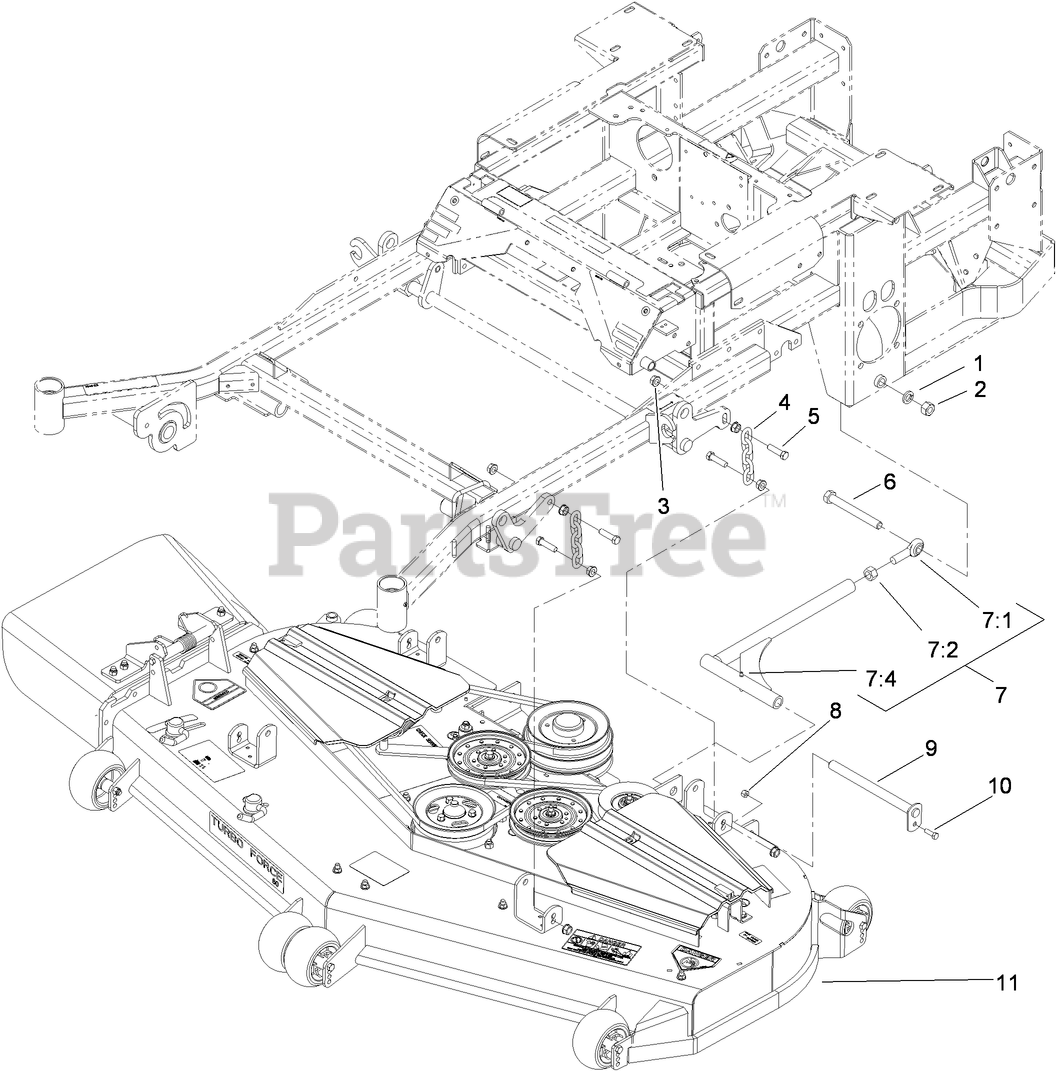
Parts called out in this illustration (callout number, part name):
1	WASHER-LOCK
2	NUT-HEX
3	NUT-HF
4	CHAIN-LIFT, DECK
5	SCREW-HH
6	SCREW-HH
7	STRUT ASM
7:1	BALLJOINT-SPHERICAL
7:2	NUT-HEX
7:4	FITTING-GREASE
8	NUT-LOCK, NI
9	PIN-STRUT
10	SCREW-HH
11	DECK ASM
